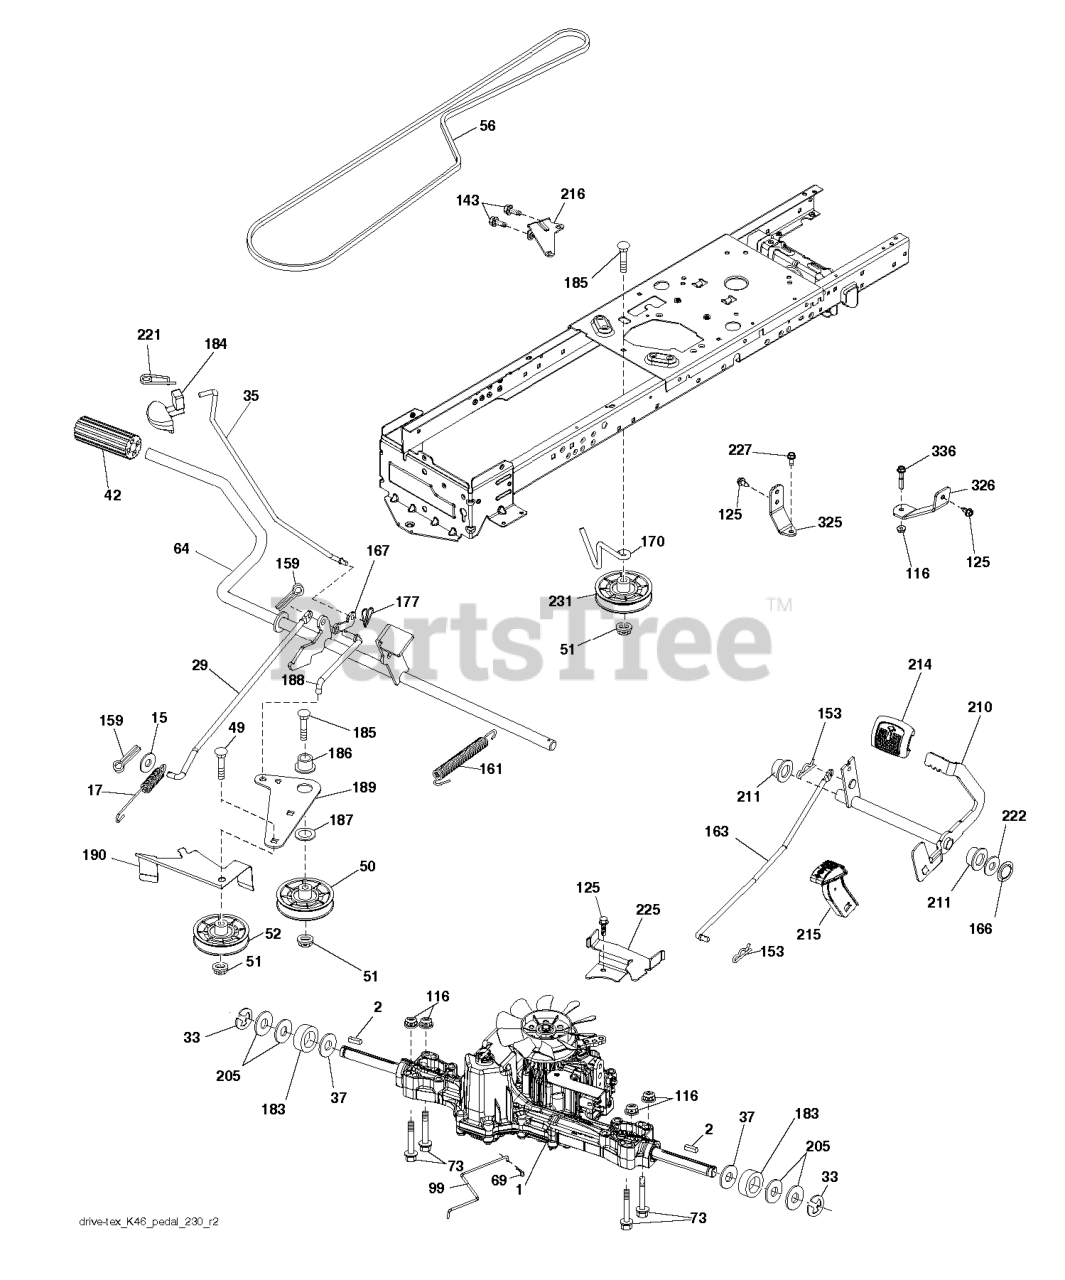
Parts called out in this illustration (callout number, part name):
1	TRANSAXLE(K46BT).PDL.
2	SQUARE KEY
15	WASHER PLAIN WASHER 3/8 X 0.08
17	SPRING.BRAKE.K46.GREEN
29	ROD.BRAKE.K46
37	WASHER.HARDENED
42	PEDAL COVER
50	IDLER.FLAT.910.OFFSET
51	NUT LOCK FLG 3/8-16 UNC
52	IDLER.V-GROOVE.910.OFFSET
64	SHAFT.ASM.PEDAL.BRK.CNTR
69	HAIRPIN.SOFT.ZINC.059X1.125
99	ARM.PIVOTING.TCRD.GEN2.5.BAGGE
125	SCREW
153	RETAINER M
161	SPRING, RETURN LT
166	NUT.PUSH.625
167	LATCH.BRAKE.SPRING
170	KEEPER.CENTER SPAN.1.688
177	PIN COTTER;LOCKING;BOWTIE;1IN
183	SPACER AXLE
184	HANDLE.PARKNG BRK.PRED.LT.428
186	SPACER.RETAINER
188	LINK.CLUTCH.GROUND DRIVE.LONG
189	BELLCRANK.GROUND.DRIVE.TEX.
190	KEEPER.BELLCRANK.DRIVE
210	ROCKER.ASM.PEDAL.CONTR
211	BEARING.NYLON
214	PEDAL.FORWARD.PAD.TEX
215	PEDAL.COVER.REVERSE.CRD.X428BK
216	BRACKET.PULLEY.IDLER.W/TEX
221	RETAINER.SPRING.CLIP.H
222	WASHER 21/32 X 1-1/4 X 10 GA.
225	KEEPER.BELT.TRANSAXLE.K46
231	IDLER.V-GROOVE.1.688.OFFSET
325	TORQUE.STRAP.K46.LT.LH
326	BRCKT.PNT.TRQ.STP.46.18TIRE.RH
